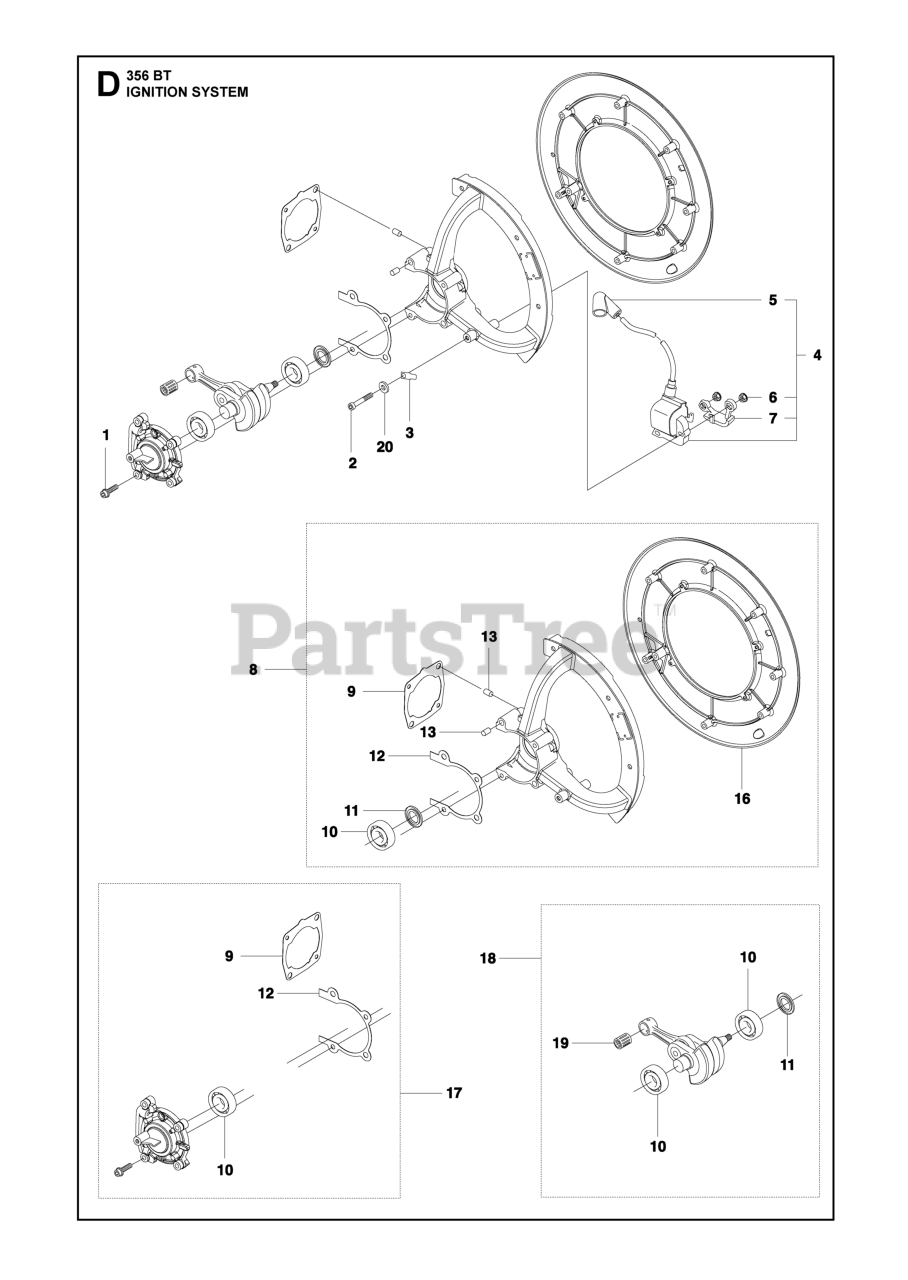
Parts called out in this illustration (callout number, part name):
1	SCREW
3	FLAT PIN
4	IGNITION SYSTEM
5	SPARK PLUG CONN. KIT
8	CRANKCASE KIT
10	BALL BEARING
18	CRANKSHAFT
19	NEEDLE BEARING PISTON PIN 12X1
20	WASHER 4.2X9
